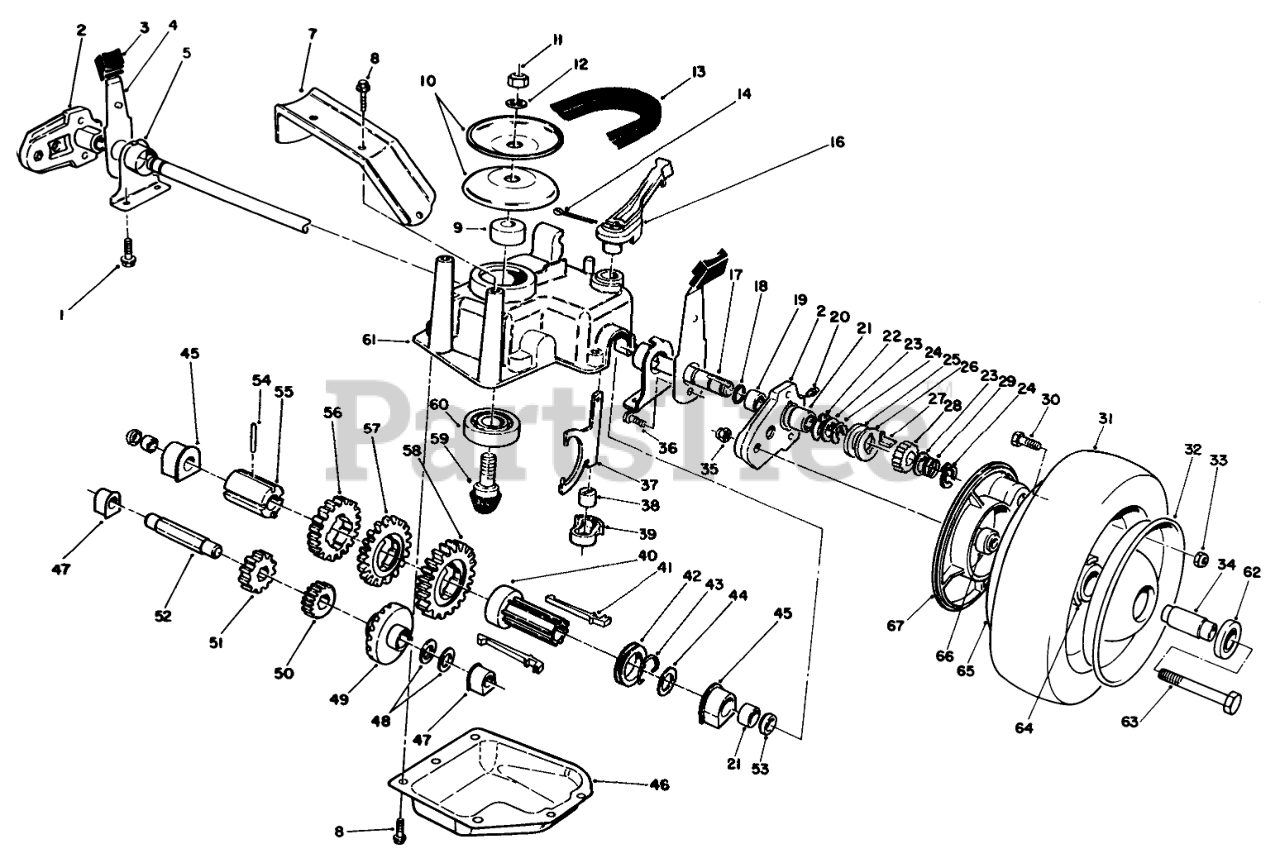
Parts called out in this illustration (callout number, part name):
1	NUT-HJ
2	Pinion Kit
3	OUTPUT SHAFT
4	R/H CLUTCH HSG ASM
5	GEAR BOX SHAFT
6	Seal
7	Bushing
8	3/16 X 1/2 ROLL PIN
9	SCREW-HSH
10	3/32X5/8 WOODRUFF KEY
11	GEAR BOX PULLEY
12	V BELT
13	Cover-Gear Case
14	Bearing
15	GASKET
16	WORM SHAFT
17	.437 NEEDLE BEARING
18	DRIVE SCREW
19	Bushing
20	L/H CLUTCH HSG ASM
21	OUTPUT SHAFT
22	NUT-JAM, LH
23	1-1/8X056 IN SNP RING
24	.375 RPP BALL BEARING
25	NUT-LOCK, NI
26	WASHER-FLAT
27	WASHER-LOCK
28	SCREW-HH
29	GEAR CASE SPACER
30	Gear Case (Incl. Ref. #6-7 & 17 & 19)
31	Support-Gear Case
32	NYLON SCREW
33	WORM GEAR
34	THRUST WASHER
35	5/32 X 7/8 ROLL PIN
